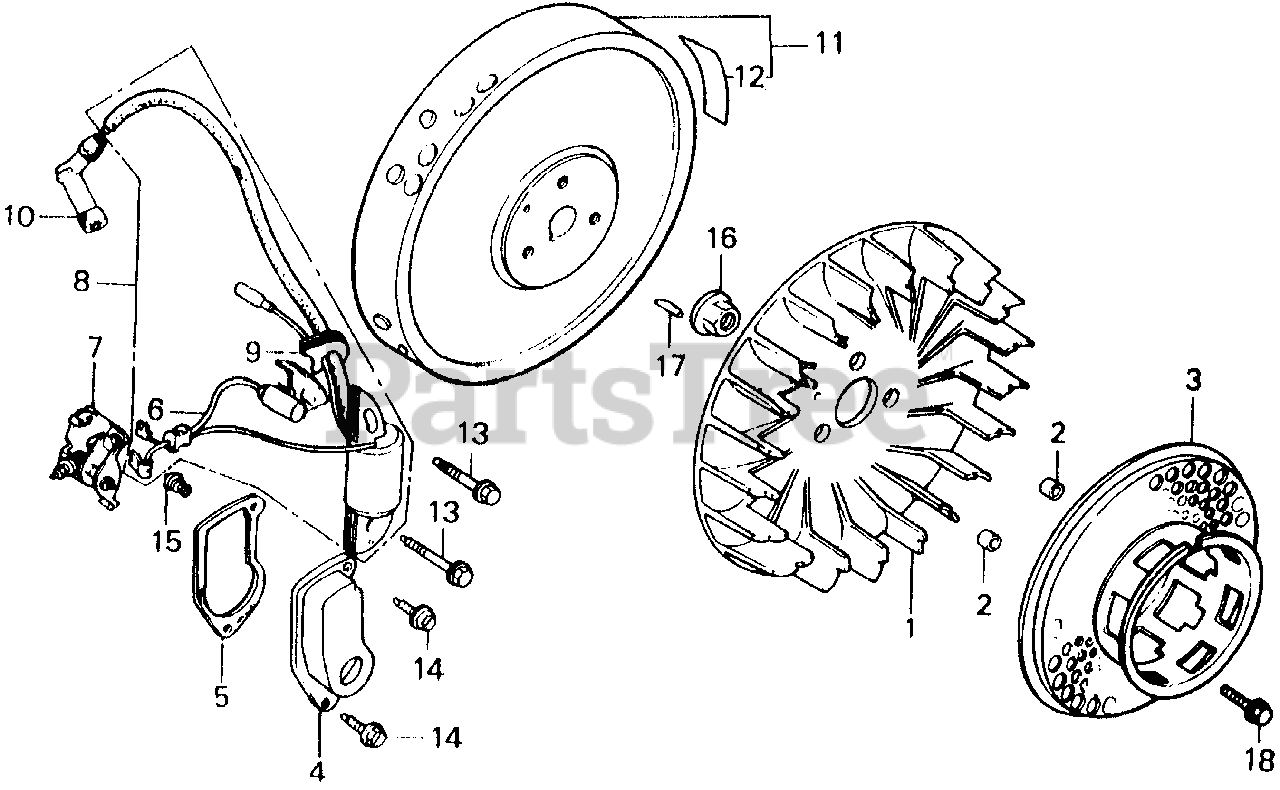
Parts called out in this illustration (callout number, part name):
1	FAN, COOLING
2	COLLAR, FAN
3	PULLEY, STARTER
4	COVER, POINTS
5	GASKET, POINT COVER
6	CONDENSER
7	POINTS ASSY.
8	COIL ASSY., IGNITION
9	GROMMET, WIRE
10	CAP ASSY., NOISE SUPPRESSOR
11	FLYWHEEL
12	MARK, FLYWHEEL CAUTION
13	BOLT, FLANGE (6X32)
14	BOLT, FLANGE (5X10)
15	SCREW-WASHER (5X12)
16	NUT, SPECIAL (14MM)
17	KEY, SPECIAL WOODRUFF (25X18)
18	BOLT, FLANGE (6X16)
